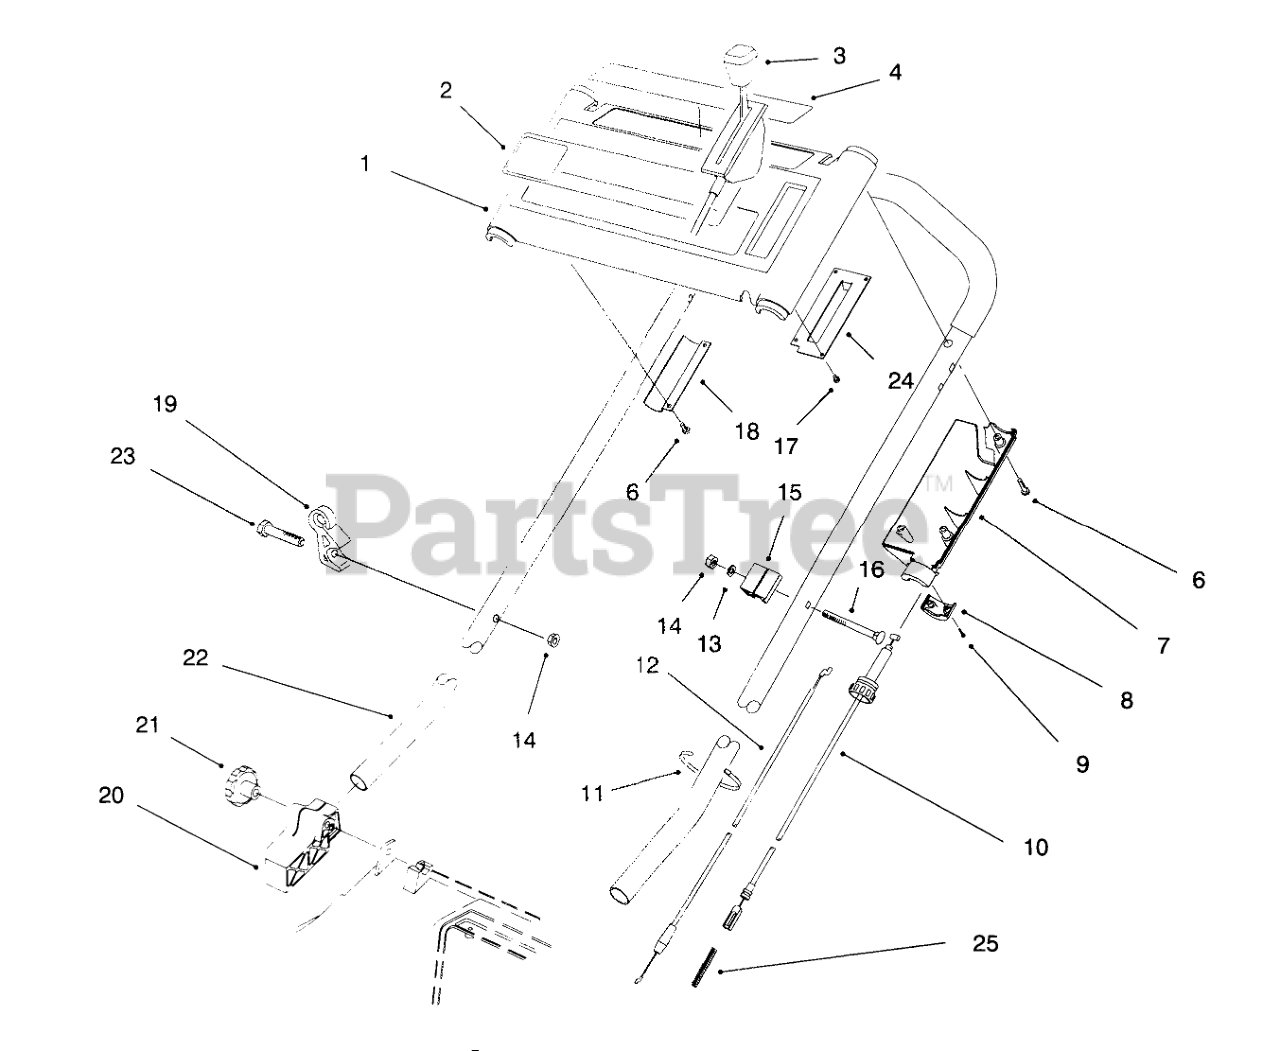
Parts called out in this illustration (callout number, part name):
1	Panel-Control (Incl. Ref. #2 & 4)
2	DECAL - PANEL OHV
3	CONTROL - THROTTLE
4	DECAL - CONTROL PANEL
6	SCREW-PPH, PLASTITE
7	COVER-THROTTLE, LEVER
8	LOWER THROTTLE CAP
9	#4-14X.62 PLASTITE SCW
10	ASM - TRACTION CABLE
11	TIE-CABLE
12	CABLE - BRAKE
13	WASHER-FLAT
14	NUT-LOCK, NI
15	SUPPORT-CABLE
16	SCREW-HANDLE
17	#6-19X.25 PLASK FORM SC
18	Bracket-Panel
19	GUIDE - ROPE
20	MOUNT-HANDLE, RH
22	Handle
23	.250-20X1.625 HH SCREW
24	THROTTLE PLATE
25	SPRING-COMPRESSION
